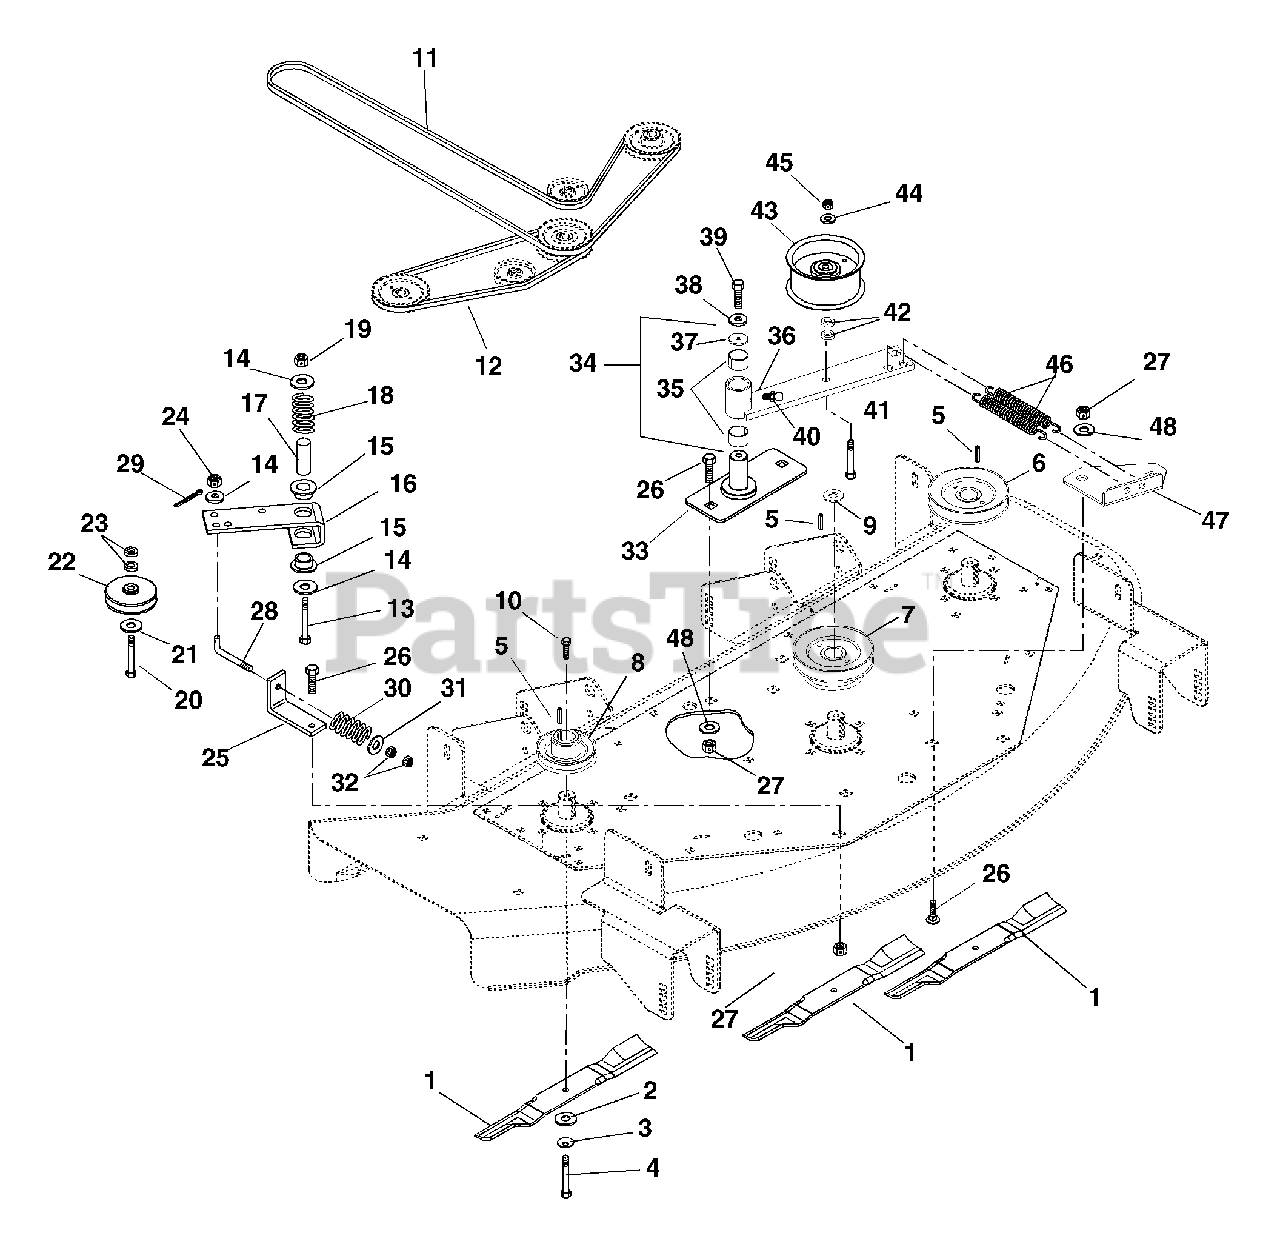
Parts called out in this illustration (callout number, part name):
1	Blade, 50" Mower
2	Washer, Flat .64 x 1.81 x .25
3	Washer-Bellville .63 x 1.625 x .14
4	Bolt, Blade
5	Key-Square .25 x 1.00 x .25
6	Weldment, Pulley-V 4.75 x 1.004 with Key
7	Weldment Pulley-Double V 4.75,3.50X1.004 with Ke
8	Weldment, Pulley-V 3.50 x 1.004 with Key
9	Washer, Cupped, Serrated .375
10	Bolt-Hex .38-16 x 1.00 Grade 8 with Epoxy Patch
11	Belt-V, A-Section 59.40 x .531
12	Belt-V, A-Section 18.05 x .495
13	Bolt-Round Head Square Neck .50-13 x 3.50 Grade 5
14	Washer-Flat-Steel .531 x 1.250 x .100
15	Bushing-Flange Nylon .762 x 1.00 x .58 x 1.48
16	Arm, Idler Pivot
17	Spacer, Steel .56 x .75 x 2.44
18	Spring-Compression .085 x .80 x 1.00
19	Nut-Locking-Center .50-13
20	Bolt-Hex .38-16 x 2.00 Grade 5
21	Washer-Flat-Steel .375 x 1.125 x .065
22	Idler-V 3 x .38
23	Bushing .406 x .750 x .188
24	Nut-Locking-Nylon .38-16
25	Bracket, Belt Tensioner
26	Bolt-Hex .50-13 x 1.25 Grade 5
27	Nut-Locking-Center .50-13
28	Rod, Idler
29	Pin-Center .09 x .75
30	Spring-Compression .125 x .78 x 1.00
31	Washer-Flat-Steel .406 x .812 x .065
32	Nut-Hex-Jam .38-16
33	Weldment, Idler Pivot
34	Assembly, Idler Pivot Arm
35	Bearing 1.000 x 1.125 x .75
36	Assembly, Idler Pivot Arm
37	Washer-Flat-Steel .380 x 1.50 x .125
38	Washer-Locking .38 x .094 Regular
39	Bolt-Hex .38-16 x 1.25 Grade 5
40	Fitting-Lube .25-28 x .256
41	Bolt-Hex .38-16 x 2.75 Grade 5
42	Bushing .406 x .750 x .188
43	Idler-Flat 4.00 x .38 (2.00 Wide)
44	Washer-Flat-Steel .375 x 1.125 x .065
45	Nut-Locking-Center .38-16
46	Spring, External .09 x 1.00 x 6.00
47	Bracket, Idler Spring
48	Washer-Flat-Steel .50 x 1.25 x .083
